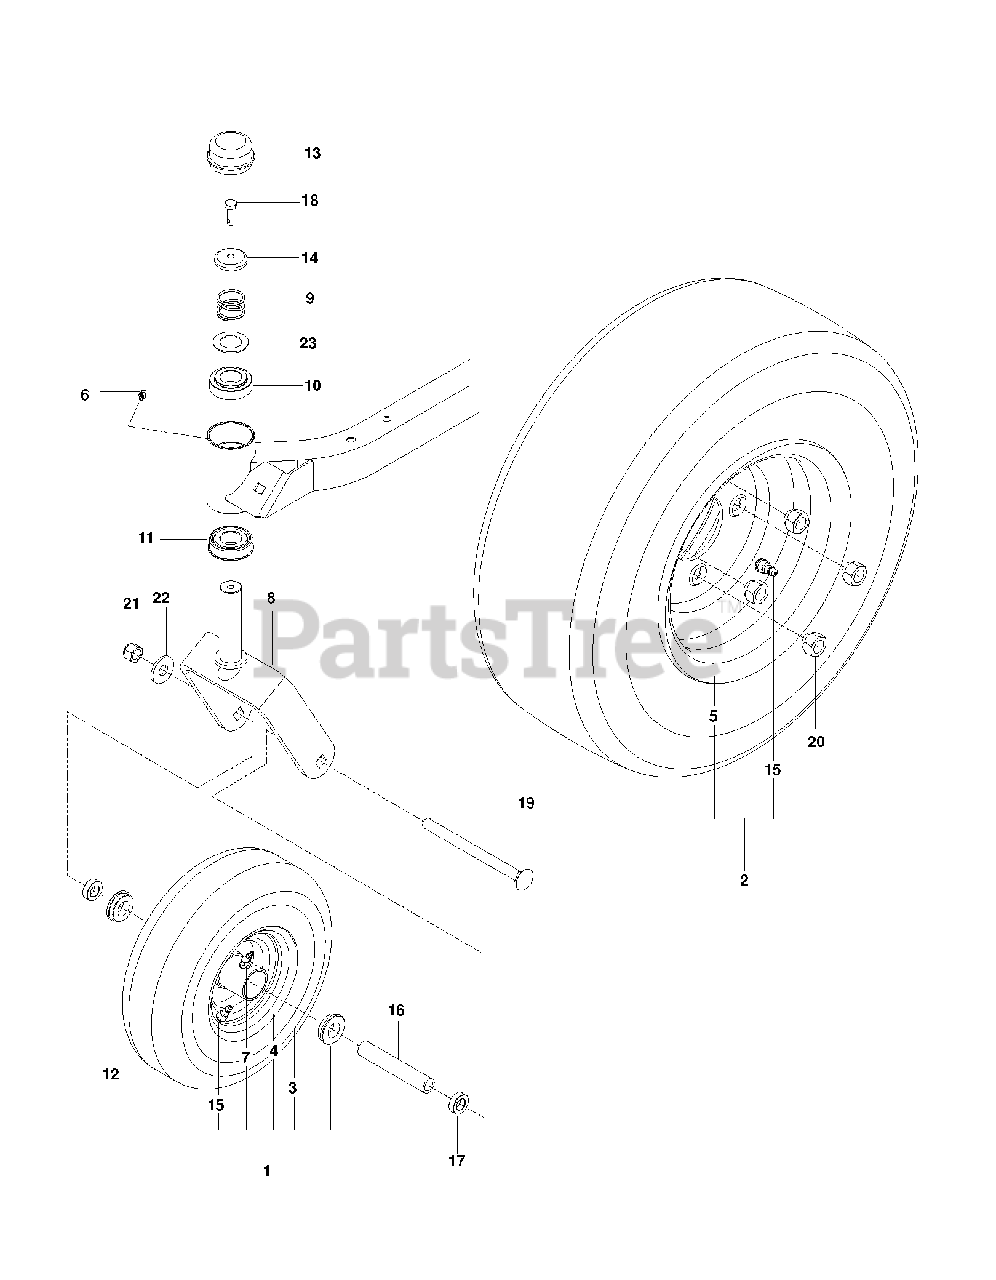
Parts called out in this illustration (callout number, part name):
1	TIRE.CASTER.ASSEM.11X4-5.GR
2	WHEEL ASM.18X8.5-8.KENDA.
3	TIRE.11"X4"-5.4PLY.SMOOTH.KEND
5	RIM.8X7.SILVER.ZTR
6	ZERK, 3/16, DRIVE IN
7	ZERK
8	YOKE.CASTER.BLACK
9	SPRING, CASTER
10	BUSHING, CASTER
11	BEARING FLANGED
12	BUSHING, WHEEL, 3/4"
13	GREASE CAP
14	CASTER.PLUG
15	VALVE STEM TR-412
17	SPACER, 5/16"
18	5/16-18X1 HHB G5W/NY
19	RHSNB 1/2-13 X 6.50 GR2 ZD
20	LUG NUT 1/2F
21	NUT 1/2-13 HEX CNTRLK GR 5 ZD
22	WASH USS FLAT 1/2
23	WASHER, 1.025 ID X 1.64
